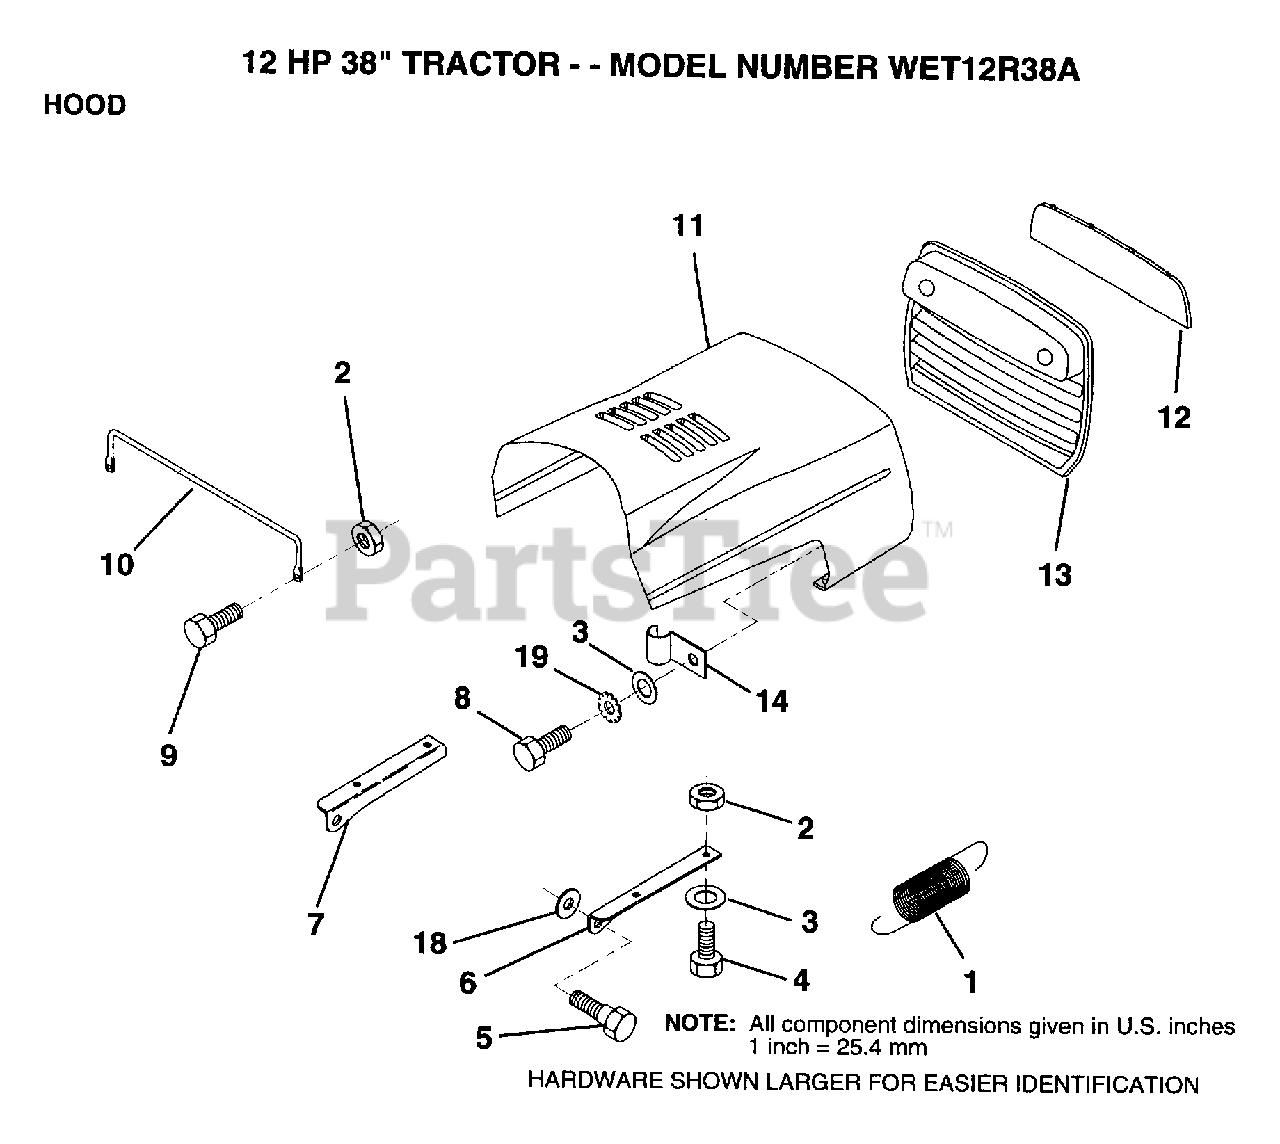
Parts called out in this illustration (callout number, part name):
1	EXT SPRING
2	NUT
3	WASHER
4	BOLT
6	BRKT HOOD RH
7	BRKT HOOD LH
10	"BRACE,HOOD"
11	HOOD
12	LENS
13	GRILL
14	CLIP T
18	WASHER
19	LOCKWASHER GT
